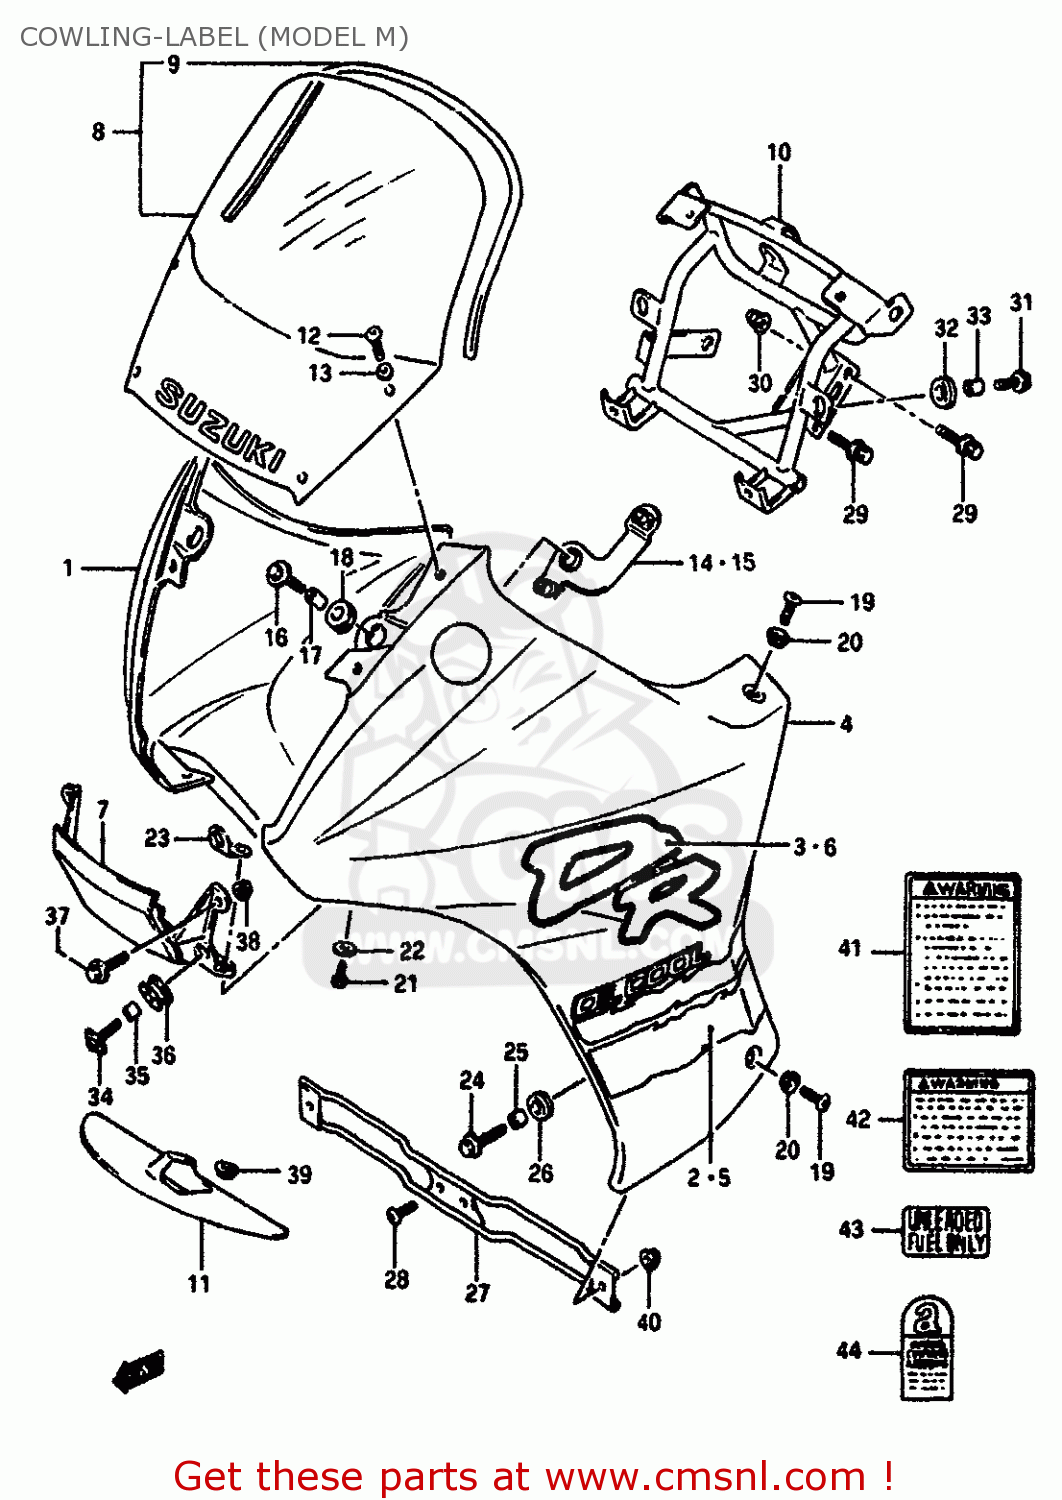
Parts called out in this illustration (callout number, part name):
1	COVER ASSY,COWL SIDE RH (RED)
2	TAPE SET,RH
3	EMBLEM
4	COVER ASSY,COWL SIDE LH (RED)
5	TAPE SET,LH
6	EMBLEM
7	COVER,COWLING CTR
8	WINDSCREEN
9	MOLDING
10	BRACE,COWLING
11	COVER,COWLING FR LWR
12	SCREW
13	WASHER(5.2X11X1)
14	BRACE,SCREEN,R
15	BRACE,SCREEN,L
16	SCREW
17	SPACER
18	CUSHION
19	SCREW(6X16)
20	WASHER(6.3X16X1.5)
21	SCREW (6X18)
22	WASHER(6.5X18X1.5)
23	BRACKET,COWLING FR LWR
24	SCREW(6X25)
25	SPACER (6.1X9X10)
26	CUSHION
27	BRACKET,COWL LOWER
28	SCREW
29	BOLT
30	NUT M8
31	BOLT 6X20
32	CUSHION
33	SPACER (6.1X9X10)
34	SCREW
35	SPACER
36	CUSHION
37	SCREW,HEADLAMP (5X20)
38	NUT 5MM
39	WASHER (6.5X18X1.6)
40	NUT
41	LABEL (WARNING SCREEN)
42	LABEL, WARNING
43	LABEL,FUEL CAUTION
44	LABEL,ASBESTOS WARNING
